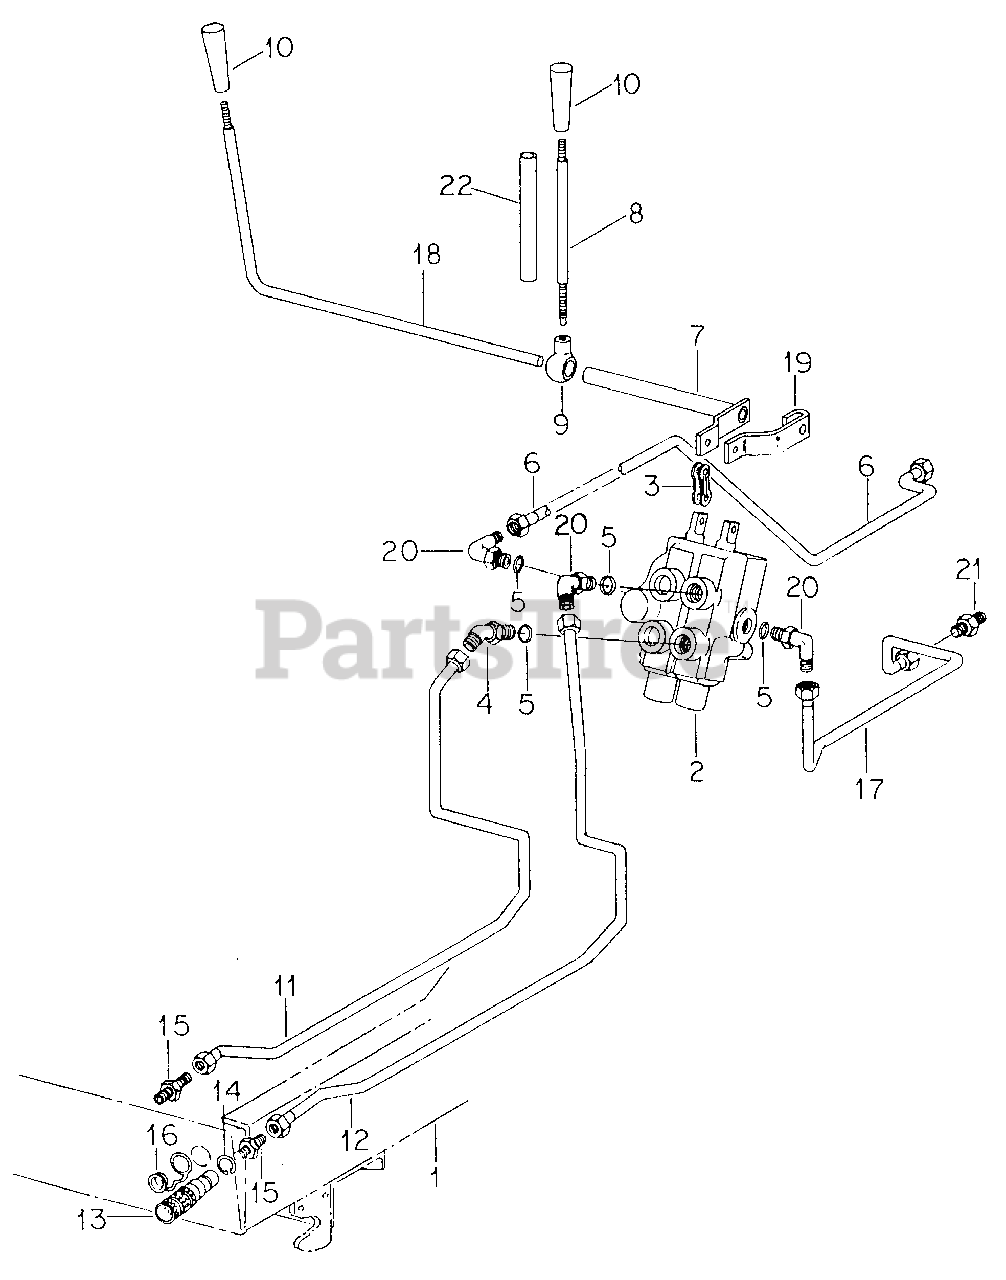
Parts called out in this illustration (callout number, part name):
1	Frame Assy, Front Outlets
2	Valve Assy, Two Spool Control
3	Link, Chain
4	Elbow, 9/16-18 C-Z 37 Deg Hyd Flared Tube Adj Str Thd 45 Deg
5	O-Ring, 3/8 OD Tube
6	Tube, Return
7	Shaft Assy, Valve Handle
8	Handle, Valve
9	Hub, Valve Handle
10	Grip, Handle
11	Tube, Pressure Supply Upper
12	Tube, Pressure Supply Lower
13	Body, Hyd Coupling
14	Ring, External Ret
15	Connector, 1/4-18 Ptf X 9/16-18 C-Z 37 Deg Hyd Flared Tube
16	Plug, Protective
17	Tube Assy, Pressure
18	Handle, Valve
19	Lever Assy, Valve Handle
20	Elbow, 9/16-18 C-Z 37 Deg Hyd Flared Tube Adj Str Thd 90 Deg
21	Union, 9/16-18 C-Z 37 Deg Hyd Flared Tube Short Swivel
22	Tube, Valve Handle
